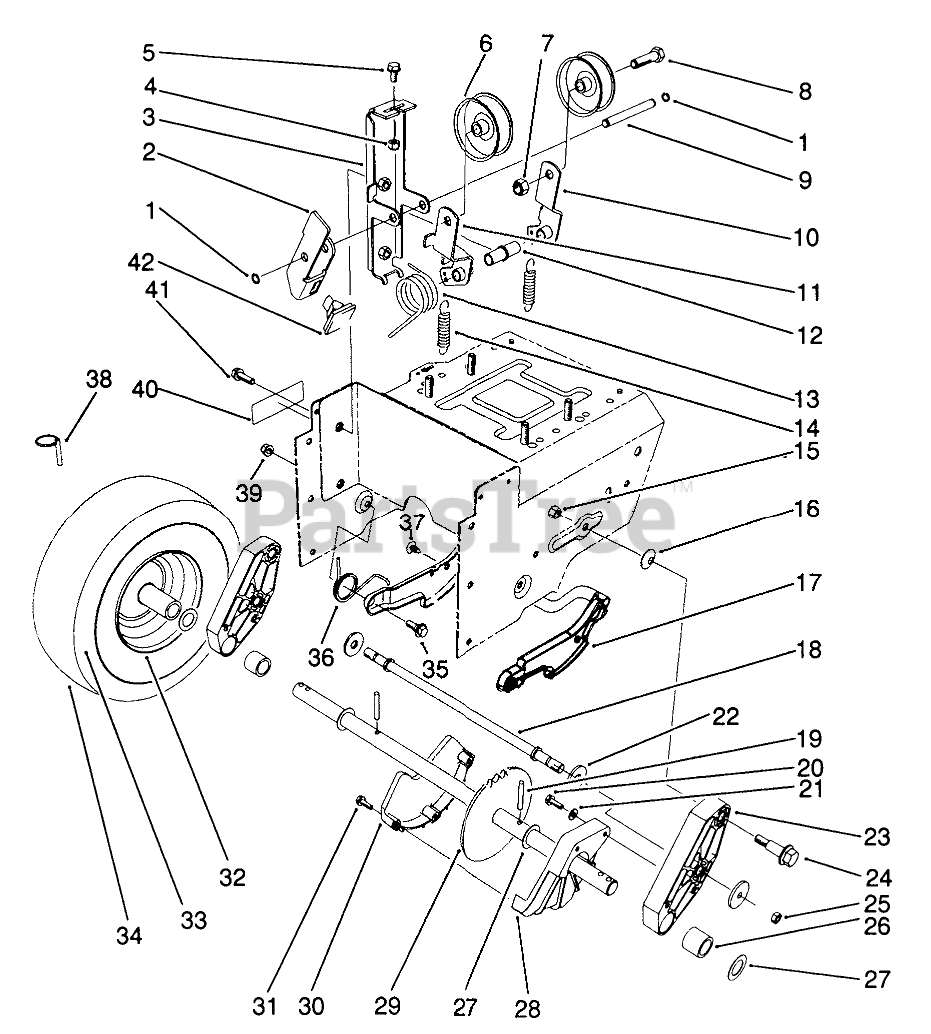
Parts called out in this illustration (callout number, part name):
1	RING-RETAINING
2	ARM-BRAKE
3	IDLER ARM BRACKET ASM
4	NUT-LOCK, NI
5	SCREW-HHF
6	PULLEY-IDLER
7	NUT-LOCK, NI
8	SCREW-HH
9	PIN-IDLER
10	ARM-IDLER, TRACTION
11	ARM-IDLER, IMPELLER
12	BUSHING-IDLER
13	TORSION SPRING
14	SPRING-EXTENSION
15	NUT-LOCK, NI
16	WASHER-SPRING
17	Latch-Arm
18	ROD-LATCH
19	PIN-ROLL, SLOTTED
20	SCREW-HWH
21	WASHER-FLAT
22	WASHER-SUPPORT
23	Pivot Arm Assembly (Incl. Ref. #26)
24	BOLT-SHOULDER
25	NUT-LOCK, NI
26	BUSHING-AXLE
27	WASHER-THRUST
28	GUARD-CHAIN, LH
30	GUARD-CHAIN, RH
31	Screw
32	RIM-WHEEL
33	INNER TUBE
35	SCREW-SHOULDER
36	SPRING-LATCH, TORSION
37	FASTENER-PANEL
38	PIN-LYNCH
39	NUT-LOCK, NI
40	DECAL-WARNING
41	SCREW-HHF
42	PAD-BRAKE
